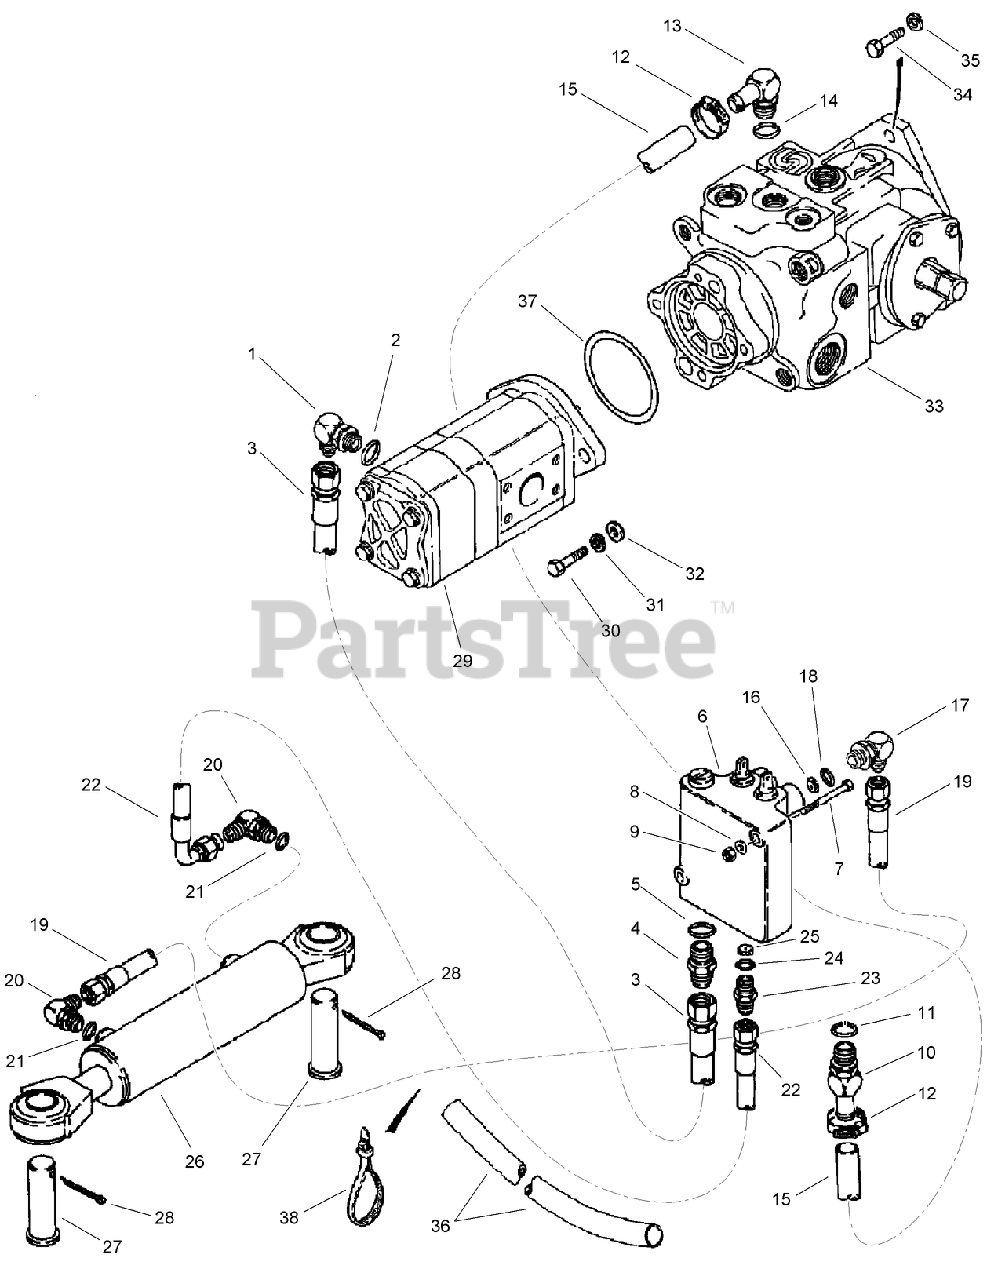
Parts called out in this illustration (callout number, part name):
1	ELBOW-90 Deg, 1/2 to 5/8
2	O-RING
3	HOSE - 610 mm (24 inch) Long, Pump to Steering Control Valve
4	CONNECTOR-Str Thd 1/2, 37FL-ORB 1/2
5	O-RING
6	HYD STEERING VALVE ASM
7	BOLT-1/4-20 x 2
8	WASHER-FLAT
9	NUT-Prev Trq 1/4 GRC PHC Direct
10	ADAPTER - Straight, 3/4 Stem End x 3/4-16 inch Adj O-Ring
11	O-RING
12	CLAMP - Adj, 11/16 - 1-1/4 inch Dia
13	ELBOW - 90 Degree, 3/4 Stem End x 1-1/16-12 inch Adj O-Ring Boss
14	O-RING - 59/64 ID x 7/64 inch Wide
15	HOSE - 800 mm (31-1/2 in), Return, Steering Control Valve to Dual Pump
16	PLATE-ORIFICE
17	ELBOW-90 DEG (ADJUSTABLE 37 DEG)
19	HOSE - 940 mm (37 inch) Long, Valve to Steering Cylinder, Rod End
20	ELBOW-90 DEG (ADJUSTABLE 37 DEG)
22	HOSE - 737 mm (29in) Long, Valve to Steering Cylinder, Closed End
23	CONNECTOR-Str Thd 3/8, 37FL-ORB 3/8
25	ORIFICE - 0.0520 inch, Restrictor, Steering Cylinder Rod End Circuit
26	CYLINDER ASSEMBLY - 60 (2-3/8in) ID x 127 mm (5in) Stroke, Steering
27	PIN-CLEVIS
28	PIN-COTTER
29	PUMP ASSEMBLY - Dual
30	BOLT
31	WASHER-Spring Lock, Reg 3/8 ZND
32	WASHER-FLAT
33	HYD VARIABLE PUMP ASM
34	BOLT-Hex Hd 1/2 x 1-1/4 GR5 ZND
35	WASHER-Spring Lock Reg 1/2 ZND
36	SLEEVE - Hose Retaining, Protective, Hose
38	STRAP - Tie, 15 inch, Nylon, Retaining
